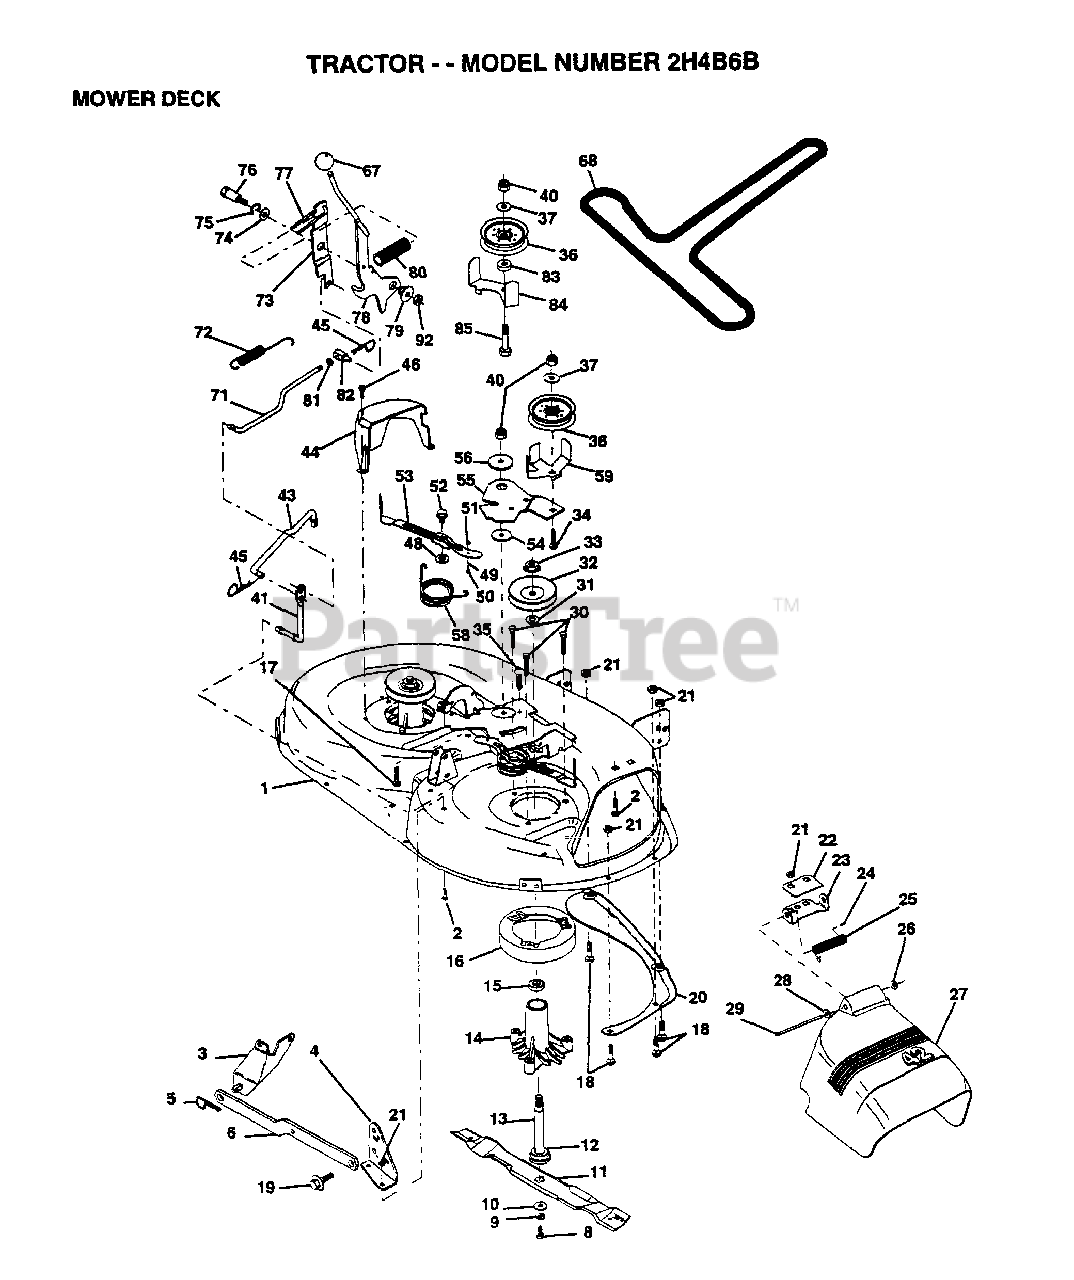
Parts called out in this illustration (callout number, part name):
1	DECK.WELD.42.
2	BOLT
3	BRKT ASM SWAY BAR
4	BRKT DECK SW BAR
8	BLADE BOLT
10	WASHER.HARD.BLADE
11	"BLADE.42"" HIPERF"
12	BEARING.BALL
14	HSG ASM MANDREL
15	BEARING
16	STRIPPER RND MWR
17	BOLT RDHD 3/8-16
18	BOLT
19	BOLT SHD 5/16-18
22	STIFFENER BRKT
23	DEFLECTOR BRKT
24	CAP-SLEEVE LT
25	SPRING TORSION
26	NUT PUSH M
27	DEFLECTOR.SHIELD
28	WASHER
29	HINGE ROD
31	WASHER
34	BOLT
35	XMAS TREE FASTNER
36	FLAT IDLER PULLEY
37	WASHER
41	PIVOT ROD
43	ROD CLUTCH W/NIBS
44	GUARD MAND LH BLK
45	RETAINER M
46	SCREW.1/4-20X5/8
48	HARD SMALL WASHER
50	SHOULDER BOLT
51	LOCKNUT
52	BOLT.SHLD.5/16-18
53	BRAKE PAD ARM ASM
54	HARDENED WASHER
56	SPACER RETAINER
58	SPRING TORSN BRAK
59	GUARD IDLER TUV
67	KNOB T(3/8 HOLE)
68	BELT.V.T-PATH
71	ROD CLUTCH 38/42
72	RETURN SPRING
73	CLUTCH ARM SECOND
74	WASHER
75	RING
76	SHOULDER BOLT
77	SPRING KEEPER
79	BUSHING
81	NUT
82	TRUNION ADJ
83	WASHER
85	BOLT
92	NUT
